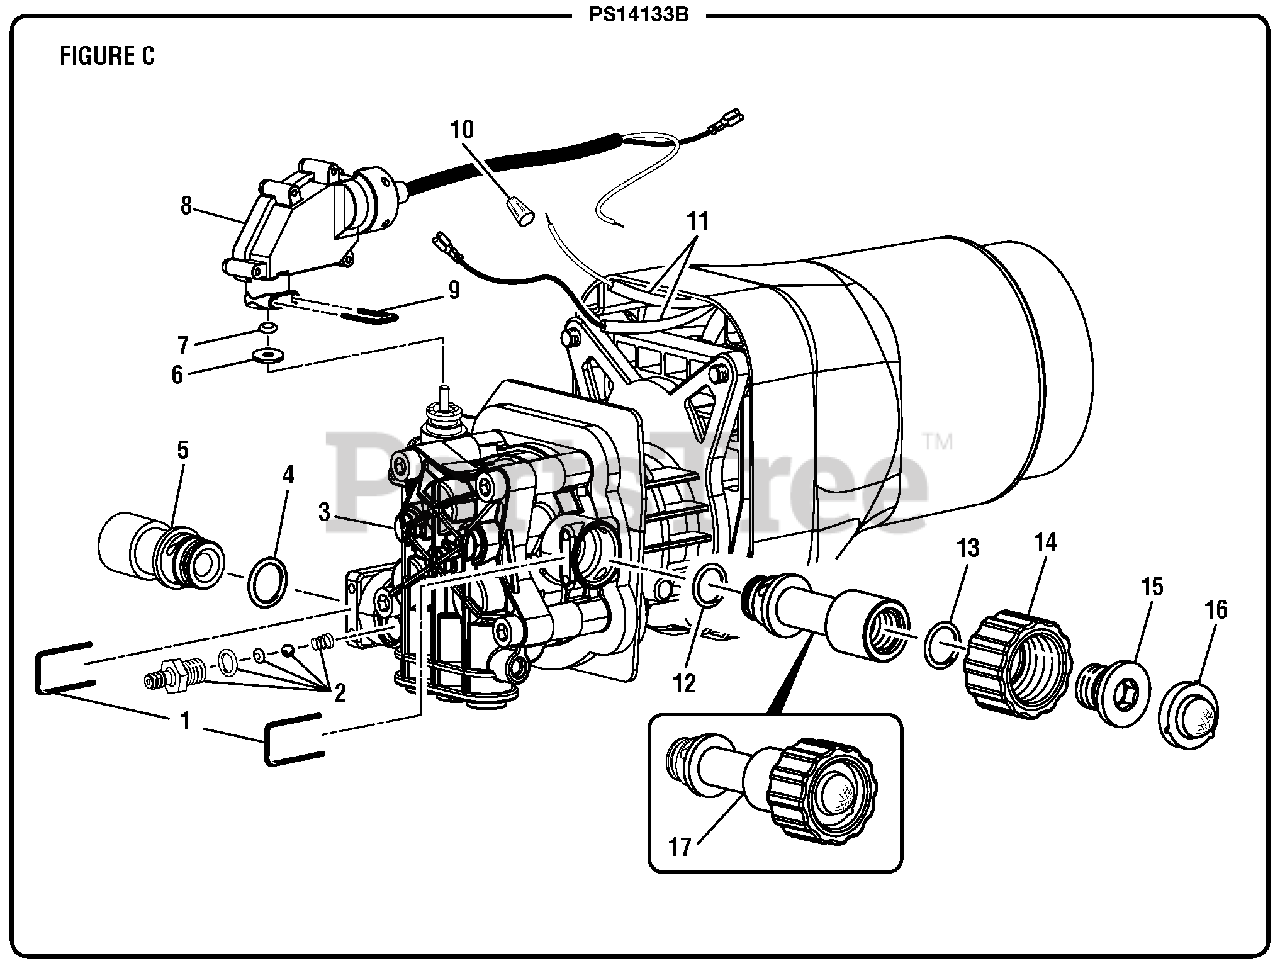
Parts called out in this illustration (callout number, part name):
1	"U" Clip (3.0 Dia.)
2	Detergent Nipple Assembly
3	Motor and Pump Assembly
4	O-Ring (ID14.5 x 1.8t)
5	Outlet Tube Assembly
6	Washer (Brass)
7	O-Ring (ID2.9 x 1.8t)
8	Pressure Switch
9	"U" Clip (2.2 Dia.)
12	O-Ring (ID12.5 x 1.8t)
13	O-Ring (ID13.5 x 1.8t)
14	Water Inlet Connector
15	Water Inlet Screw Nut
16	Water Inlet Filter
17	Inlet Tube Assembly
